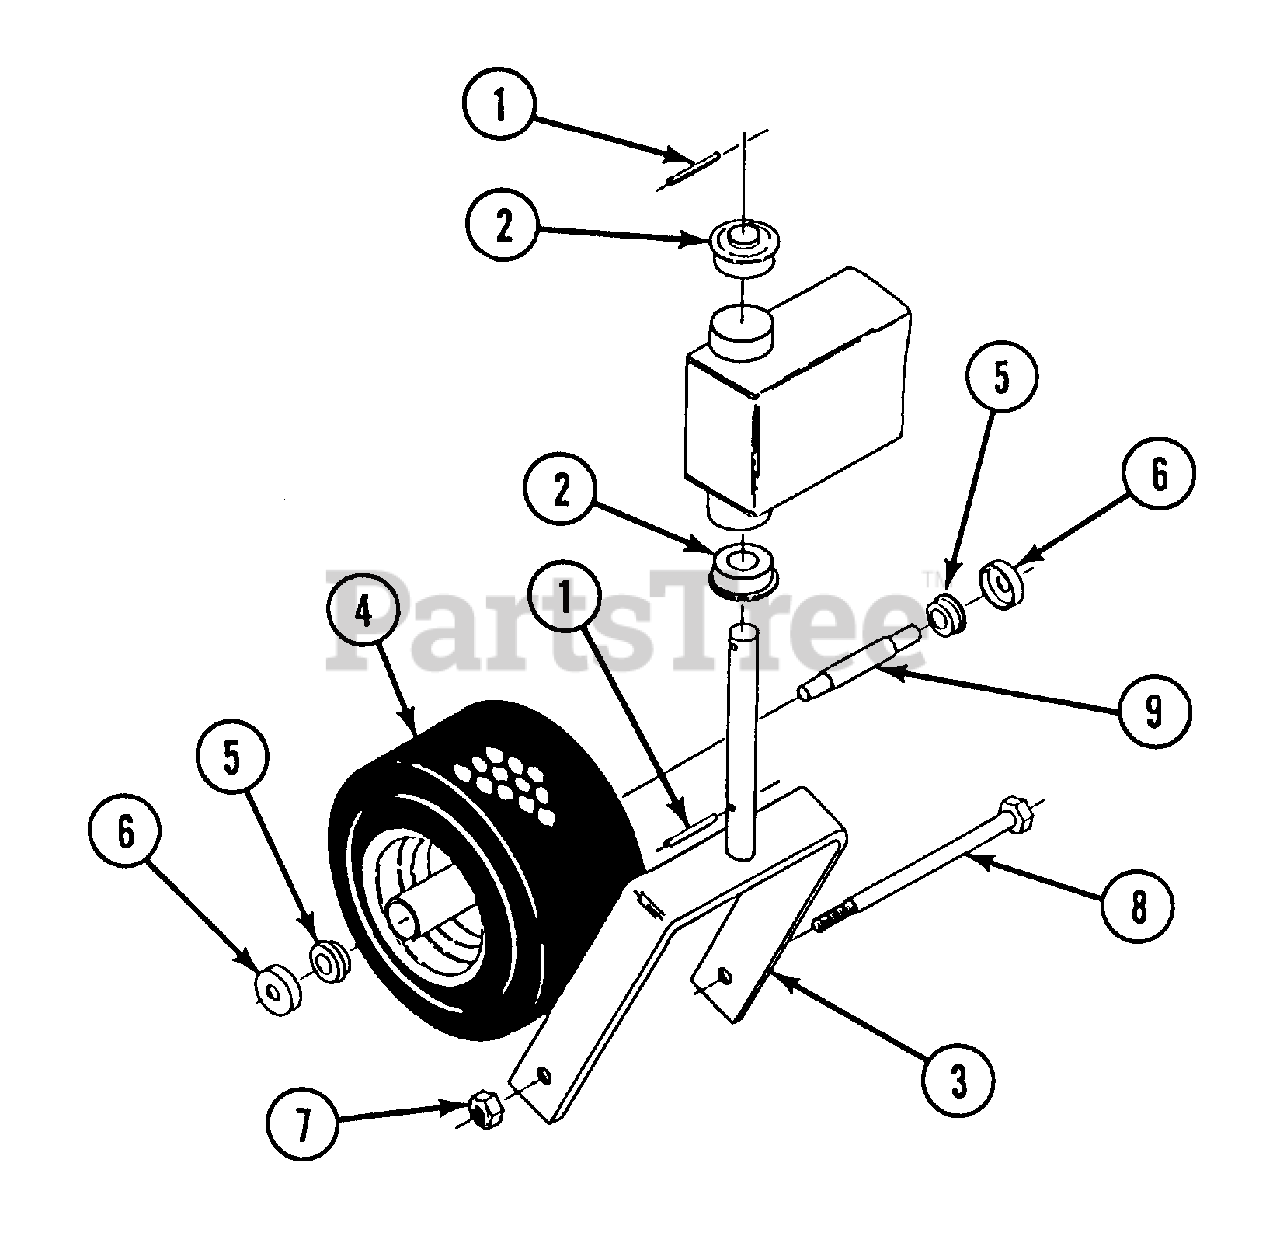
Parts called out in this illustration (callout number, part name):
1	ROLL PIN, HEAVY DUTY: 3/16 X 2
2	BEARING, SPD SF-16-32 W/0 COLLAR
3	CASTER WELDMENT
4	WHEEL, (TIRE & RIM) (10")
5	BEARING, 5/8 I.D. X 1-3/8 O.D.
6	BEARING PROTECTOR
7	LOCKNUT - NYLOCK: 1/2-13
8	AXLE, CAPSCREW, HX HD: - 1/2-13 X 7-1/2
9	SPACER, BEARING
